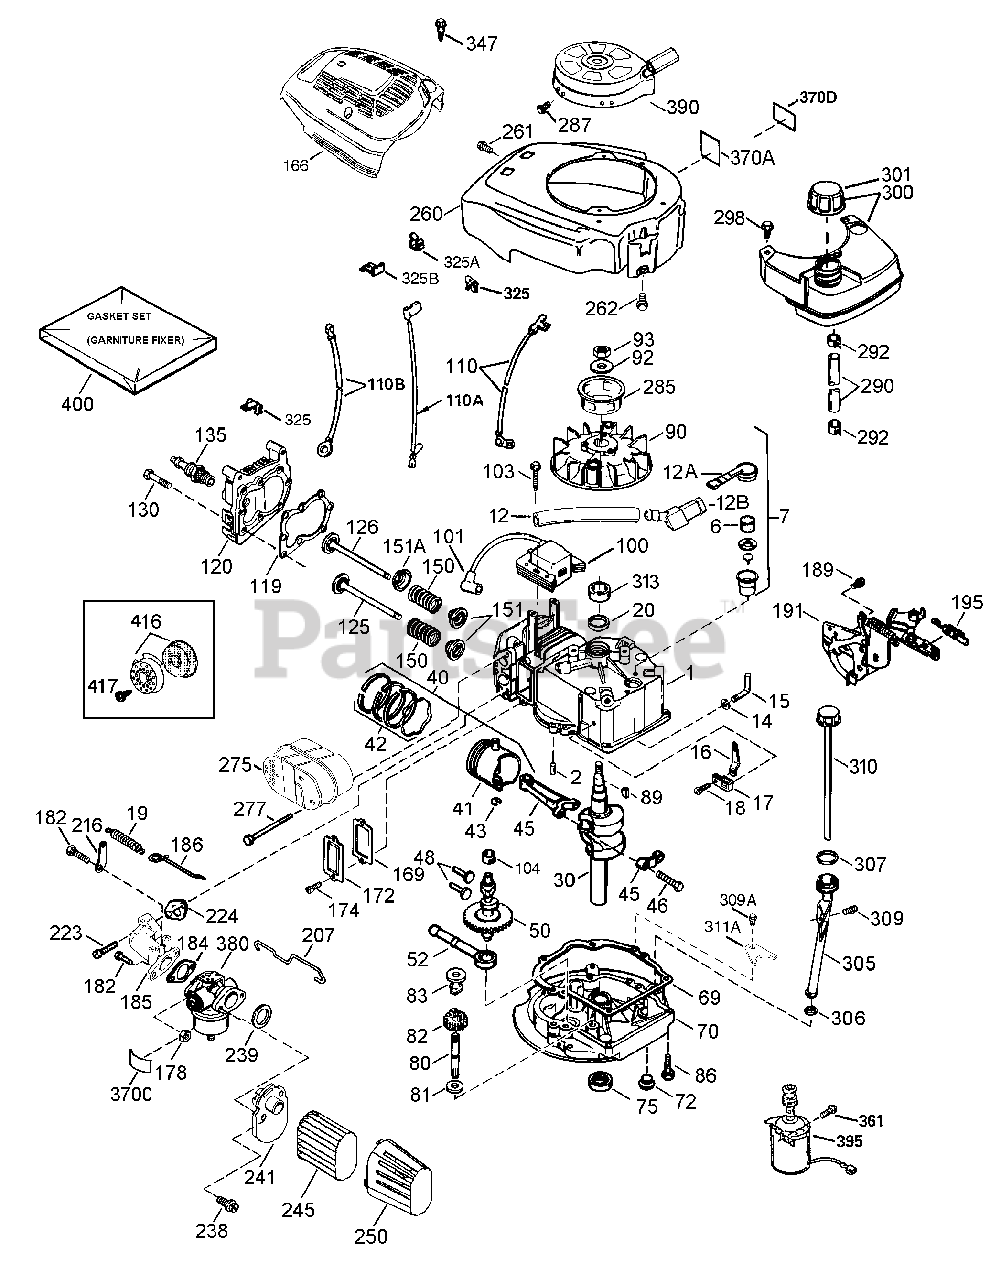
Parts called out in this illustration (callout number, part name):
1	Cylinder (Incl. 2, 20 & 150)
2	Dowel Pin
6	Breather Element
7	Breather Ass'y. (Incl. 6 & 12A)
12	Breather Tube
12A	Breather Cover & Tube (Incl. 12B)
12B	Breather Tube Elbow
14	Washer
15	Governor Rod (Incl. 14)
16	Governor Lever
17	Governor Lever Clamp
18	Screw, T-15, 8-32 x 19/64"
19	Extension Spring
20	Oil Seal
30	Crankshaft
40	Piston, Pin & Ring Set (Std.)
41	Piston & Pin Ass'y. (Std.)(Incl. 43)
42	Ring Set (Std.)
43	Piston Pin Retaining Ring
45	Connecting Rod Ass'y. (Incl. 46)
46	Connecting Rod Bolt
48	Valve Lifter
50	Camshaft (Exhaust MCR)(Inc. 104)
52	Oil Pump Ass'y
69	Mounting Flange Gasket
70	Mounting Flange (Incl. 72-83,306,309A & 311A)
72	Oil Drain Plug
75	Oil Seal
80	Governor Shaft
81	Washer
82	Governor Gear Ass'y. (Incl. 81)
83	Governor Spool
86	Screw, 1/4-20 x 1-1/4"
89	Flywheel Key
90	Flywheel
92	Belleville Washer
93	Flywheel Nut
100	Solid State Ignition
101	Spark Plug Cover
103	Screw, T-15, 10-24 x 15/16"
104	Cam Bushing
110	Ground Wire
110A	Wire Ass'y
110B	Wire Ass'y
119	Cylinder Head Gasket
120	Cylinder Head
125	Exhaust Valve (1/32" OS)(Incl. 151)
125	Exhaust Valve (Std.)(Incl. 151)
126	Intake Valve (Std.)(Incl. 151 & 151A)
130	Screw, 5/16-18 x 1-7/16"
135	Resistor Spark Plug (RJ19LM)
150	Valve Spring
151	Valve Spring Cap
151A	Intake Valve Seal
166	Engine Shroud (Green)
169	Valve Cover Gasket
172	Valve Cover
174	Screw, 10-24 x 9/16"
178	Nut & Lock Washer, 1/4-28
182	Screw, 1/4-28 x 7/8"
184	Carburetor To Intake Pipe Gasket
185	Intake Pipe
186	Governor Link
189	Screw, 1/4-20 x 3/8"
191	S.E. Brake Bracket (Incl. 195)
195	Terminal
207	Throttle Link
216	R.P.M. Adjusting Lever
223	Screw, 1/4-20 x 1"
224	Intake Pipe Gasket
238	Screw, 10-32 x 49/64"
239	Air Cleaner Gasket
241	Air Cleaner Collar
245	Air Cleaner Filter
250	Air Cleaner Cover
260	Blower Housing
261	Screw, 10-24 x 9/16"
262	Screw, 1/4-20 x 1/2"
275	Muffler
277	Screw, 1/4-20 x 2-9/32"
285	Starter Cup
287	Screw, 8-32 x 21/64"
290	Fuel Line
292	Fuel Line Clamp
298	Screw, 10-32 x 35/64"
300	Fuel Tank (Incl. 292 & 301)
301	Fuel Cap Ass'y
305	Oil Fill Tube
306	"O"-Ring
307	"O"-Ring
309	Screw, 10-32 x 1/2"
309A	Screw, 10-24 x 3/4"
310	Dipstick
311A	Hold Down Bracket
313	Spacer
325	Wire Clip
325A	Wire Clip
347	Screw, 10-32 x 27/32"
361	Screw, 1/4-20xl/2"
370A	Lubrication Decal
370C	Primer Decal (3 X)
370D	Warning Decal
380	Carburetor (Incl. 184)
390	Rewind Starter (NOTE: This engine could have been built with 590702 starter.)
395	Electric Starter Motor (12 Volt)
400	Gasket Set (Incl. Items Marked PK in Notes)
416	Spark Arrestor Kit (Optional)
